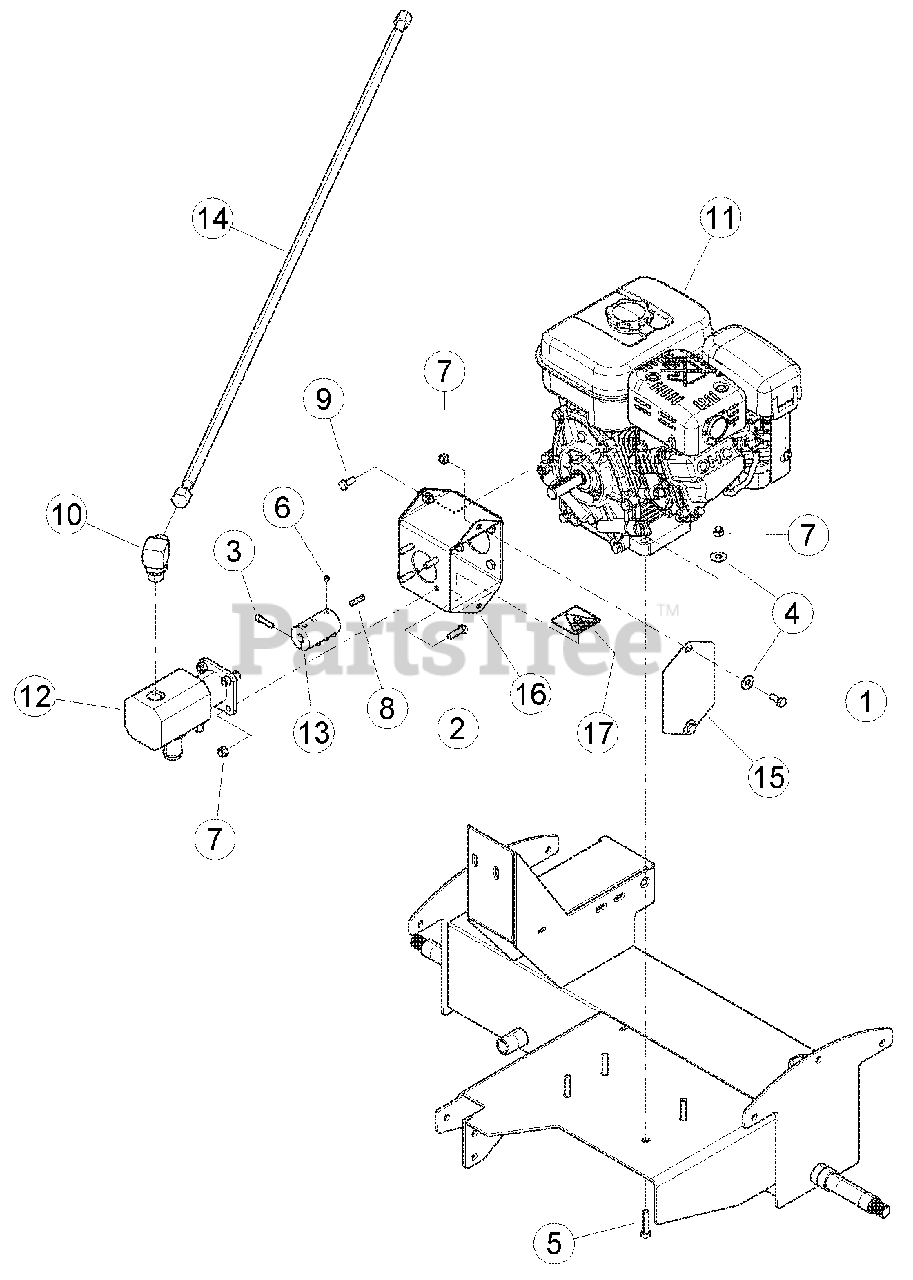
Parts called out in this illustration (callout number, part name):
1	BOLT, 5/16 X 3/4 HEX GR5 ZP
2	BOLT, 5/16 X 1 HEX GR5 NC ZP
3	BOLT, 1/4 X 1 SOC HD CAP SCRW
4	WASHER, 5/16 FLAT ZP
5	BOLT, 5/16 X 1-1/2 HEX GR5 ZP
6	SCREW, 1/4-20 X 1/4 KNR CUP SKT SET
7	NUT, 5/16 NE NYLOCK ZP
8	SQUARE KEY, 3/16 X 1 LONG
9	BOLT, 5/16-24 X 3/4 HEX GR5 NF ZP
10	ADAPTER, -10 MORING / -10 MJIC 90 DEG.
12	PUMP, LOG SPLITTER 2 STAGE
13	COUPLER, SPLIT 3/4" TO 1/2" SHAFT
14	HOSE, .50 X 50 -10 FJICSW / -10 FJICSW
15	PLATE, PUMP MOUNT COVER
16	ASSEMBLY, PUMP MOUNT, SERVICE PART
17	DECAL, SHIELD DANGER ISO
